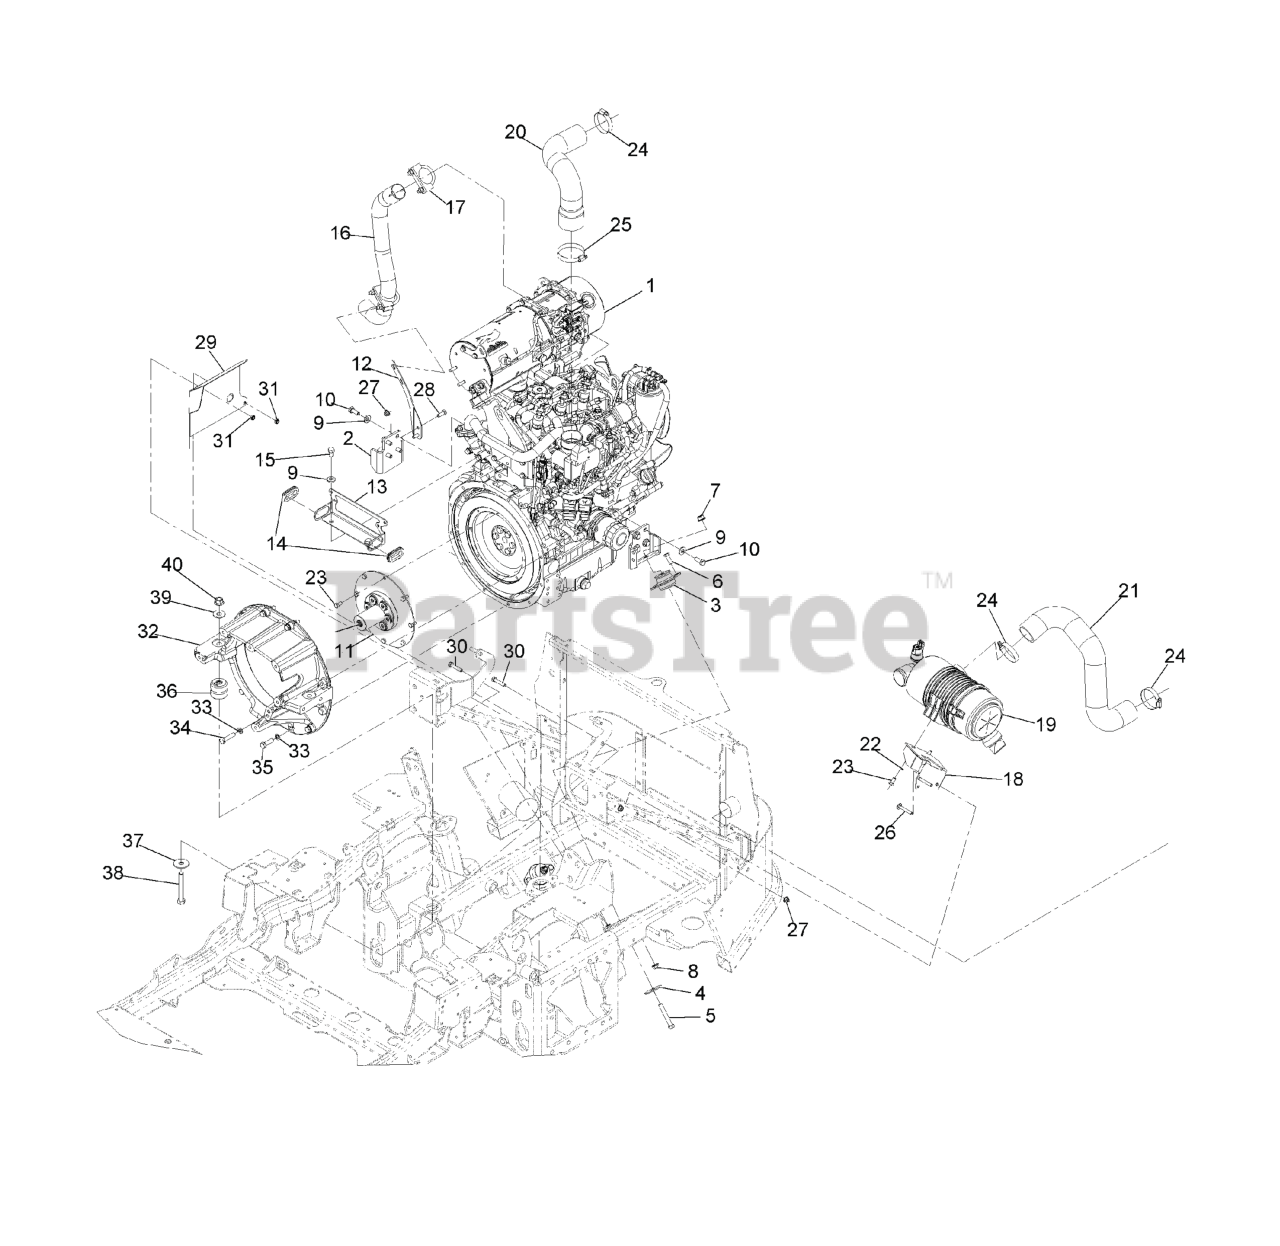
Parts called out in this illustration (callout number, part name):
1	ENGINE-YANMAR, 3TNV88C-DT
2	MOUNT-MOTOR, UPPER
4	WASHER-SNUBBING
5	SCREW-HH
6	SCREW-HH
7	NUT-HF, NI
8	NUT-HF, NI
9	WASHER-BELLEVILLE
10	SCREW-HH
11	COUPLING-FLYWHEEL
12	BRACKET-MOUNT
13	BRACKET-GUIDE
14	GROMMET-RUBBER
15	SCREW-HH
16	TUBE-EXHAUST
18	BRACKET-CLEANER, AIR
19	ASM, HDAC
20	HOSE-AIR
21	HOSE-AIR
22	WASHER-BELLEVILLE
23	BOLT
24	CLAMP-HOSE
25	CLAMP-HOSE
26	BOLT-CARR
27	NUT-HF, NI
28	SCREW-HH
29	DEFLECTOR-AIR
30	SCREW-HH
31	NUT-LOCK, NI
32	HOUSING-FLYWHEEL
33	WASHER-LOCK
34	SCREW-HH
35	SCREW-HH
36	MOUNT-ISOLATOR
37	WASHER-THRUST
38	SCREW-HH
39	WASHER-FLAT
40	Nut-Lock 1/2-13
